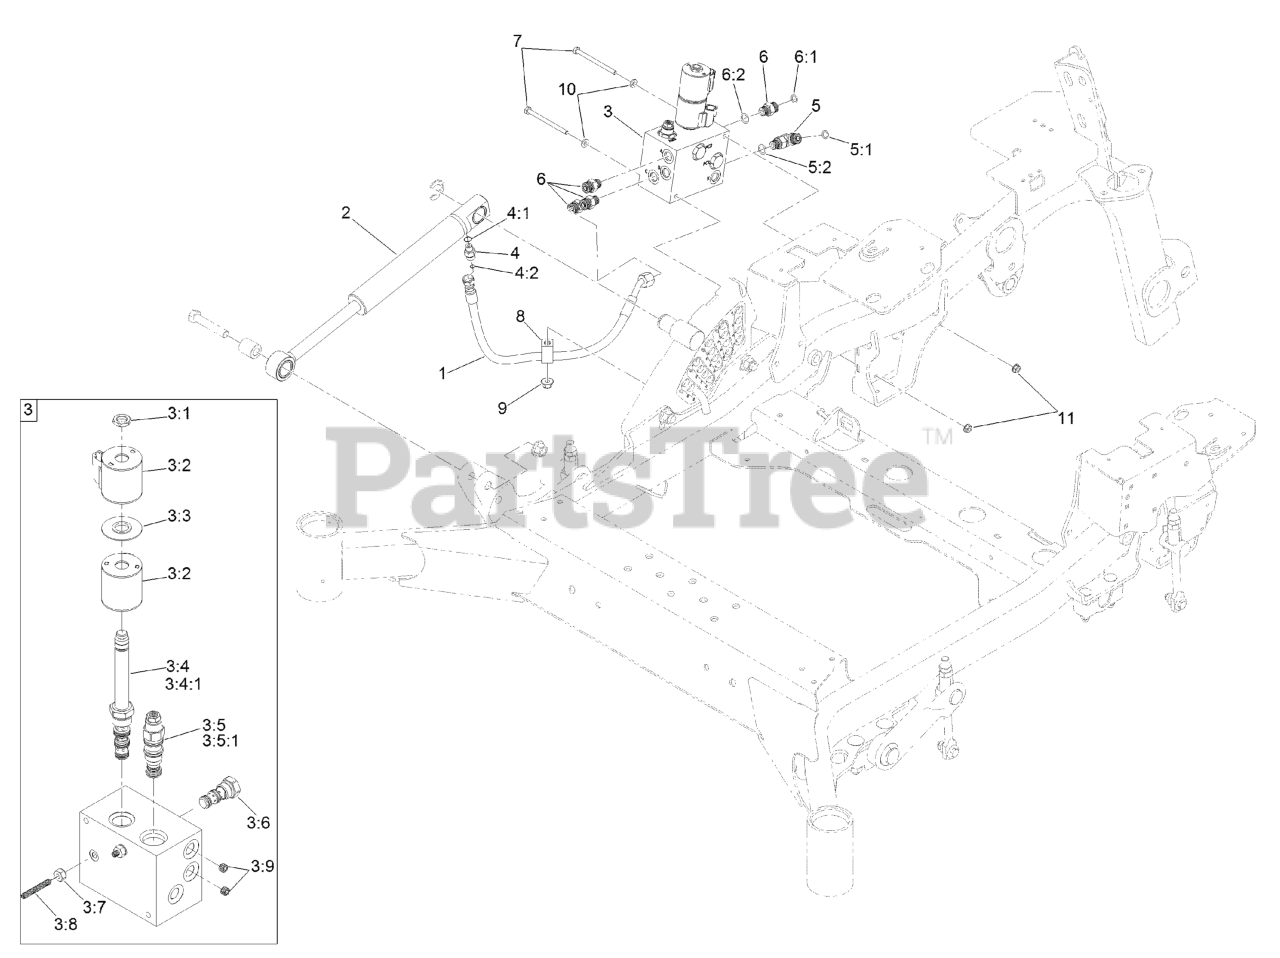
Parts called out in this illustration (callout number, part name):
1	HOSE ASM
2	CYLINDER-LIFT
3	LIFT AND HOLD VALVE ASM
3:1	NUT-COIL
3:2	COIL-12V
3:3	Spacer-E Coil
3:4	Solenoid Valve ASM
3:4:1	SPOOL VALVE SEAL KIT
3:5	VALVE-COUNTERBALANCE
3:5:1	Seal Kit
3:6	Valve-Check, Po
3:7	SCREW-SET
3:8	Nut-Sealing, Hex
3:9	Plug-Orifice (0.020)
4	FITTING-HYD, STRAIGHT
4:1	O-RING
4:2	O-RING
5	FITTING-ELBOW, 90 DEG
5:1	O-RING
5:2	O-RING
6	FITTING-STRAIGHT
6:1	O-RING
6:2	O-RING
7	SCREW-HH
8	CLIP-LOOM
9	NUT-HF, NI
10	WASHER-FLAT
